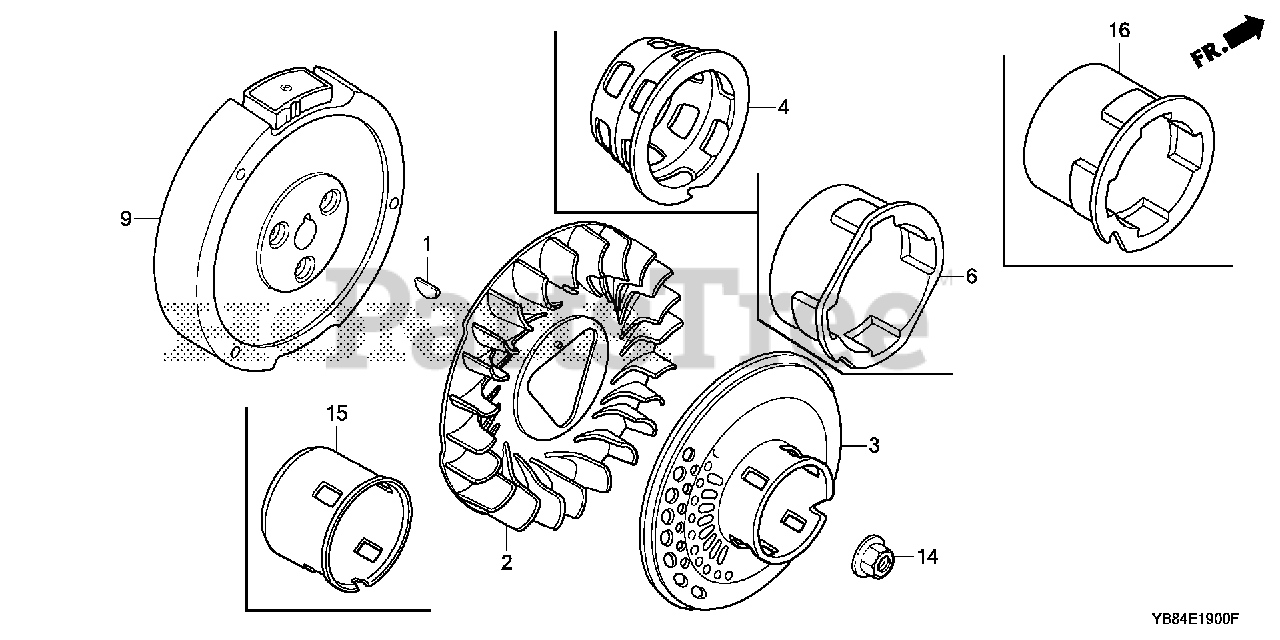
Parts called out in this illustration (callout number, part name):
1	KEY, SPECIAL WOODRUFF (25X18)
2	FAN, COOLING
9	FLYWHEEL (YUXIN)
14	NUT, SPECIAL (14MM)
16	PULLEY, STARTER
